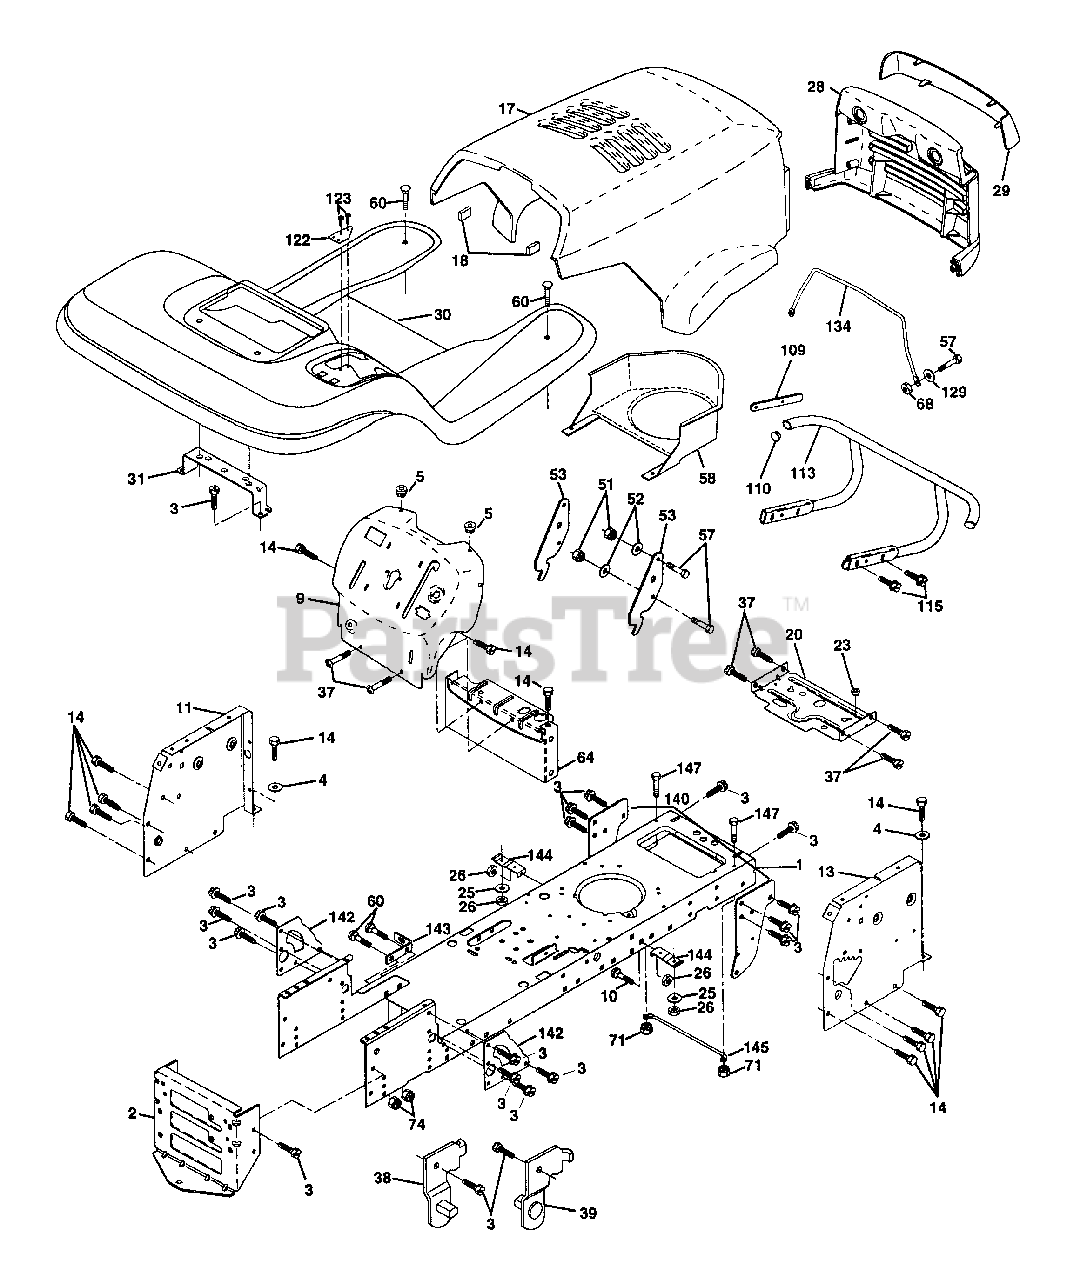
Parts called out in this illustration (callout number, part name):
1	Chassis Weldment
2	Drawbar, Stretch
3	Screw Thdrol 3/8-16x3/4 Ty-tt
4	Washer 13/32 x 3/4 x 16 Ga.
5	Bumper Hood/Dash
9	Dash Slkscr.PIm.E.A.Hm.Nc.Sym
10	Bolt Carriage 3/8-16 x 1
11	Panel Dash Lh
13	Panel Dash Rh
14	Screw Thdrol 3/8-16x1/2 Ty-tt
17	Hood LT/PL Husqvarna
18	Bumper Hood
20	Plate Mtg Battery Fuel Tank Fr
25	Washer 13/32 X 13/16 X 12 Ga
26	Nut Lock Hex W/Ins 3/8-16 Unc
28	Grille LT/PL Husqvarna
29	Lens LT/PL Husqvarna
30	Fender Footrest STLT Pnt
31	Bracket Support Fender
37	Screw Thdrol 6/16-18 x 1 /2 TYT
38	Bracket, Asm. Pivot, L.H., Mower Rear
39	Bracket, Asm. Pivot, R.H., Mower Rear
51	Nut Lock Hex W/Ins 1/4-20
52	Washer 9/32 x 7/8 x 16 Ga.
53	Bracket Pnt. Pick off LT/PL Husqvarna
57	Bolt Hex 1/4-20 x 3/4
58	Air Duct Engine P/L
60	Bolt Rdhd Sqnk 3/8-16unc x 3/4
64	Dash Lower STLT
71	Nut Crownlock 1/4-20 UNC
74	Nut Crownlock 3/8-16 UNC
109	Bracket -Extension Bumper
110	Plug Plastic
113	Bumper Asm.
115	Screw Thdrol 3/8-16 X 1-1/4 TYTT
122	Bracket Shift STLT
129	Washer 9/32 x 5/8 x 16 Ga.
134	Rod Support Hood PL Husq.
140	Bracket Suspension Front
142	Plate Reinforcement STLT
143	Bracket Swaybar Chassis
144	Bracket Pnt Footrest STLT
145	Rod Pivot Chassis/Hood
147	Bolt Hex Hd 1/4-20 UNC x 3/4
